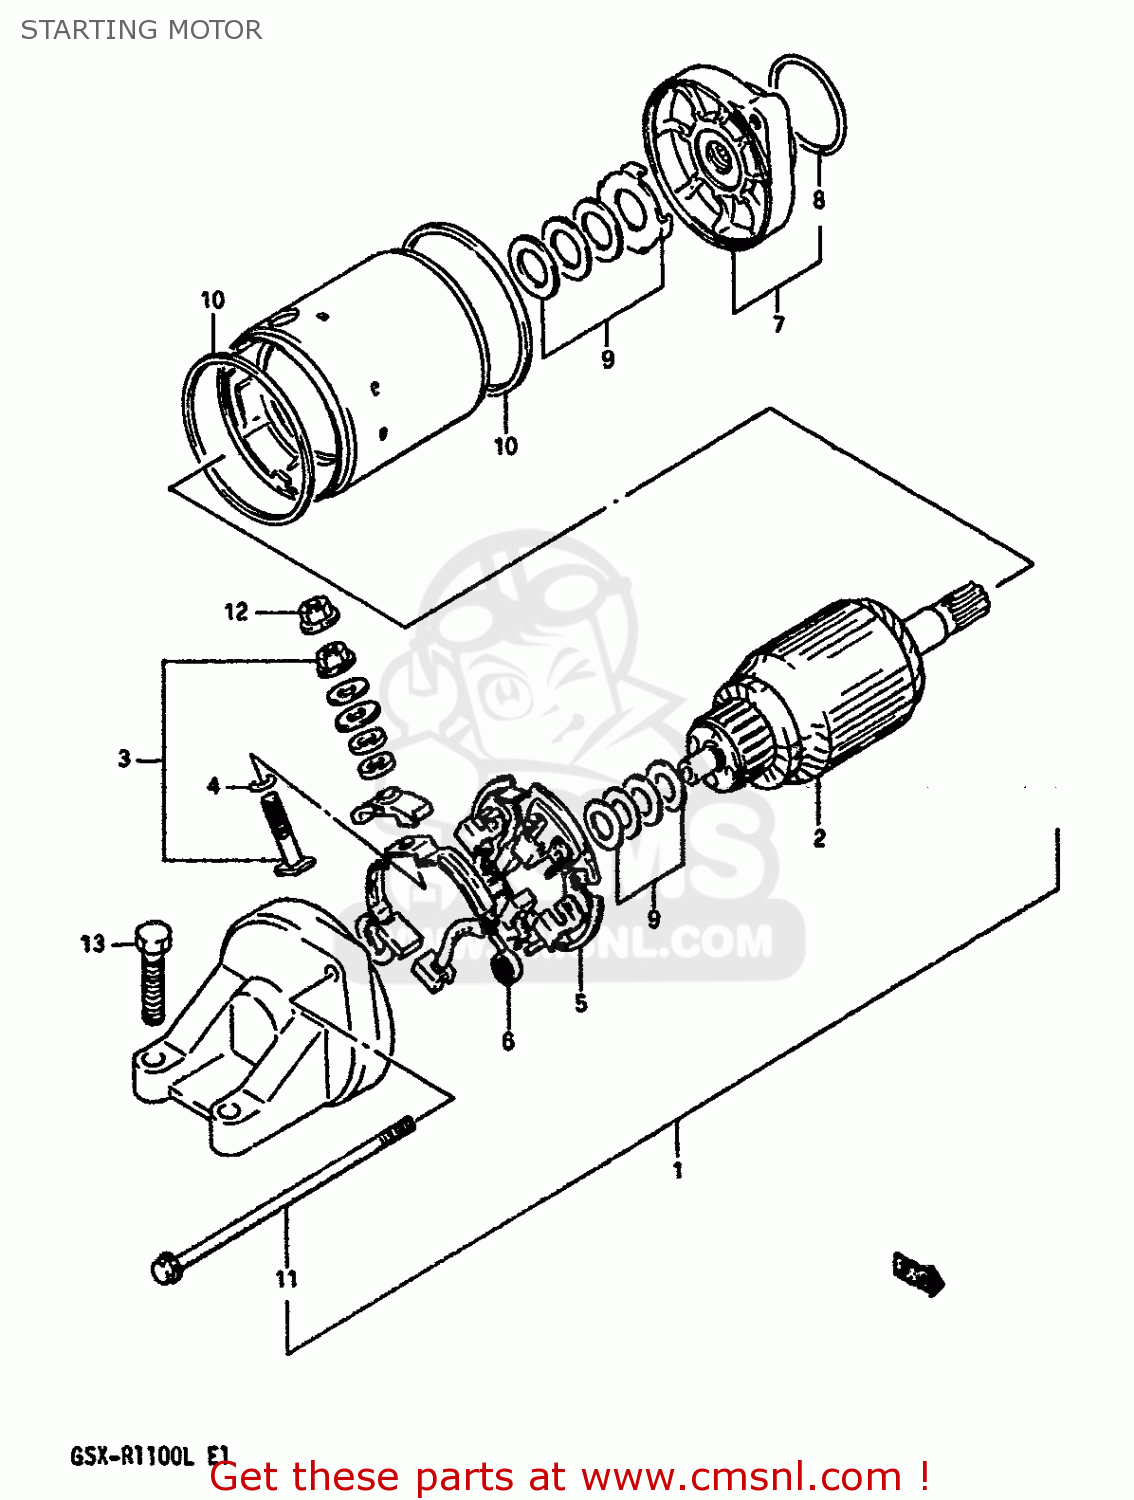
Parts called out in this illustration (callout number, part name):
1	MOTOR ASSEMBLY,STARTING
2	ARMATURE
3	TERMINAL SET,BRUSH
4	O RING
5	HOLDER SET,BRUSH
6	SPRING,BRUSH
7	BRACKET
8	O-RING
9	SHIM SET,STARTING MOTOR
10	O RING
11	BOLT
12	NUT
13	SCREW (6X25)
